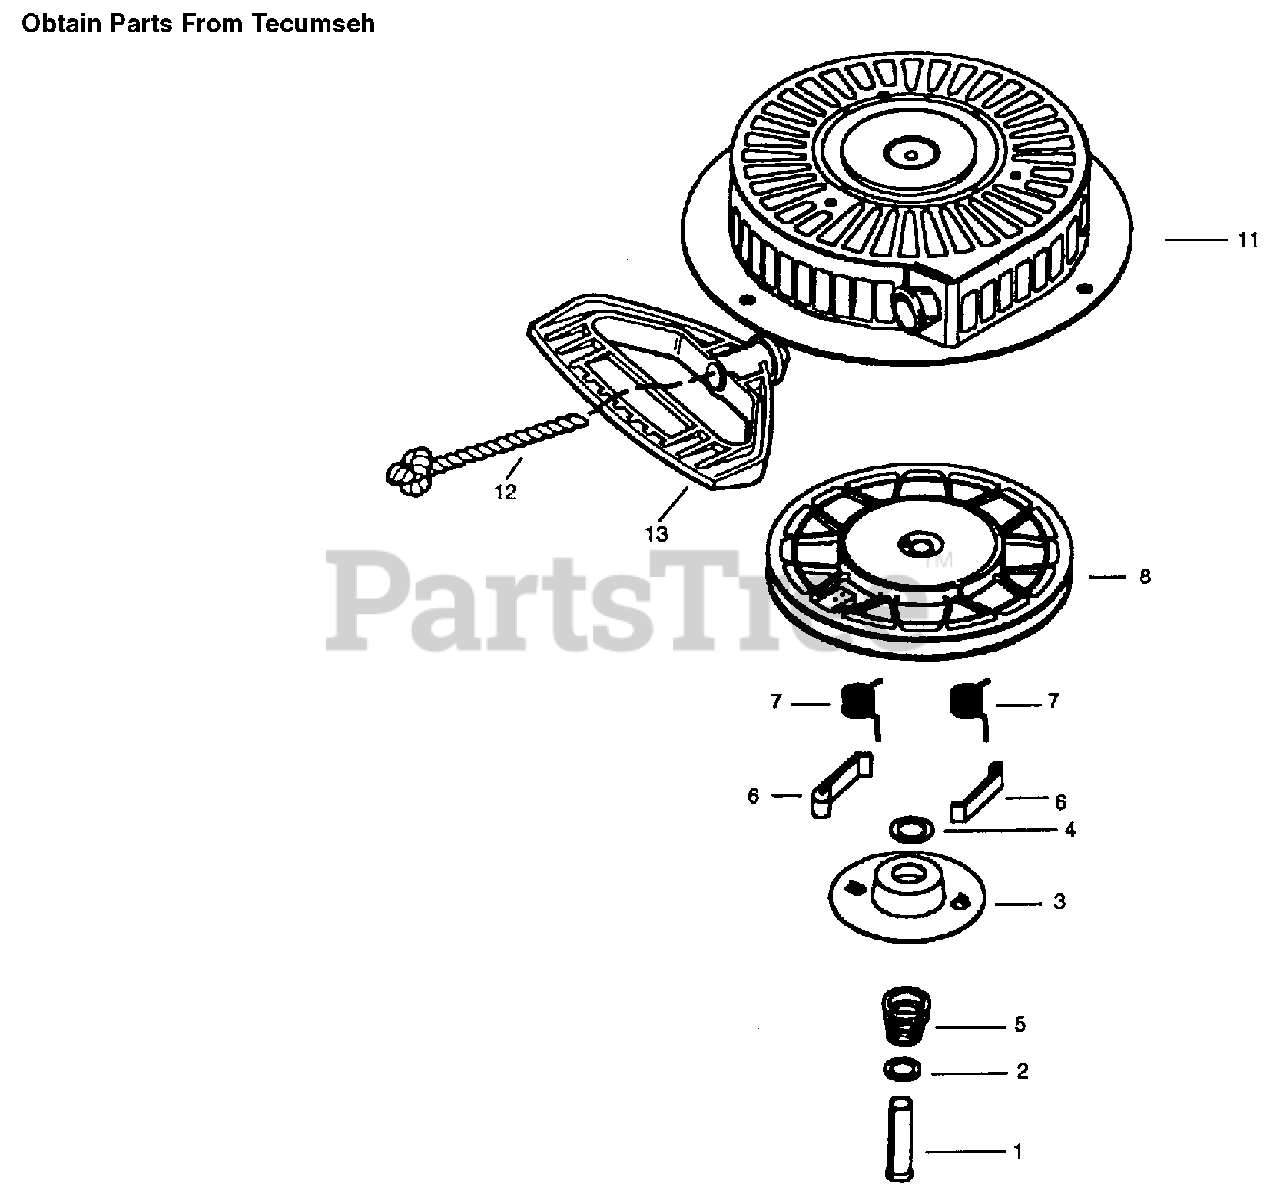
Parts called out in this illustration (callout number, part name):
1	Pin-Spring (Incl. Ref. #4)
2	Washer
3	Retainer
4	Washer
5	Spring-Brake
6	Dog-Starter
7	Spring-Dog
8	Pulley and Rewind Spring ASM
11	Starter Housing ASM
12	98 Starter Rope (cut to length)
13	Handle-Starter, Mitten Grip
